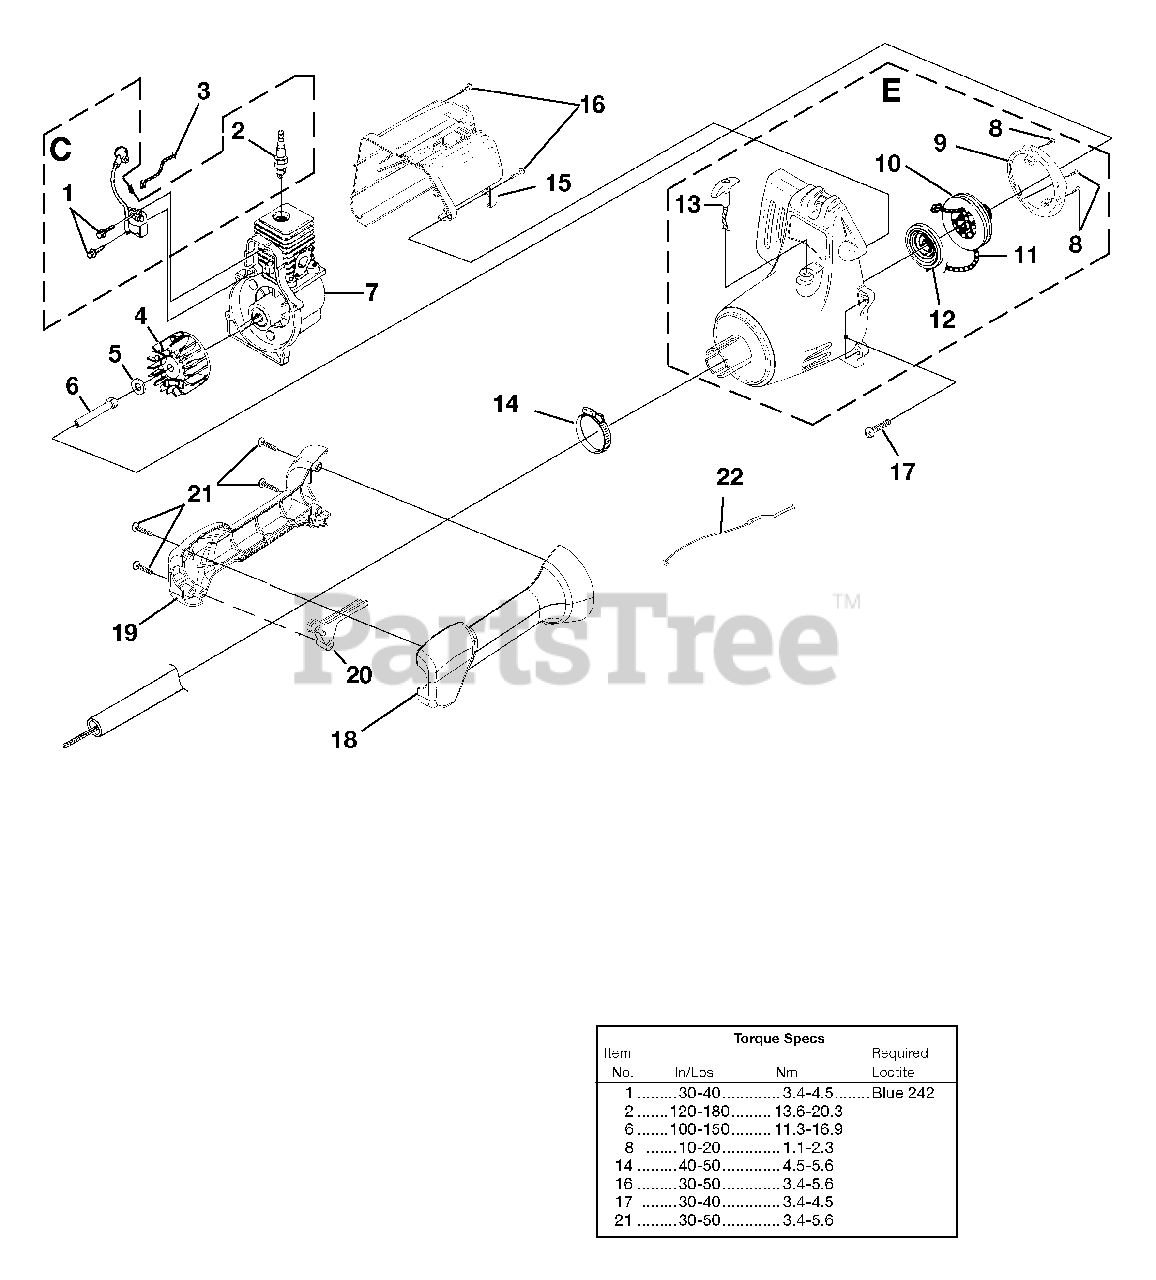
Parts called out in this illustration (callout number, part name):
1	SCREW-Taptite (8-32 x 1")
2	SPARK PLUG
3	LEAD-Electrical
4	ROTOR AND PAWL ASSY.
5	WASHER-Flat
6	CONNECTOR-Drive (.250)
7	SHORT BLOCK
8	SCREW-Taptite (8-16 x 1/2")
9	BAFFLE-Air
10	PULLEY-Starter
11	ROPE-Starter (42")
12	SPRING & CONTAINER
13	GRIP-Starter
14	CLAMP
15	HOUSING-Rear Kit
16	SCREW-Taptite (10-14 x 7/8")
17	SCREW-Taptite (10-24 x 3/4")
18	CONTROL HANDLE - (LH)
19	CONTROL HANDLE - (RH)
20	TRIGGER-Throttle
21	SCREW-Taptite (10-14 x 7/8")
22	CABLE-Throttle
C	IGNITION KIT
E	COMPLETE STARTER ASSEMBLY
